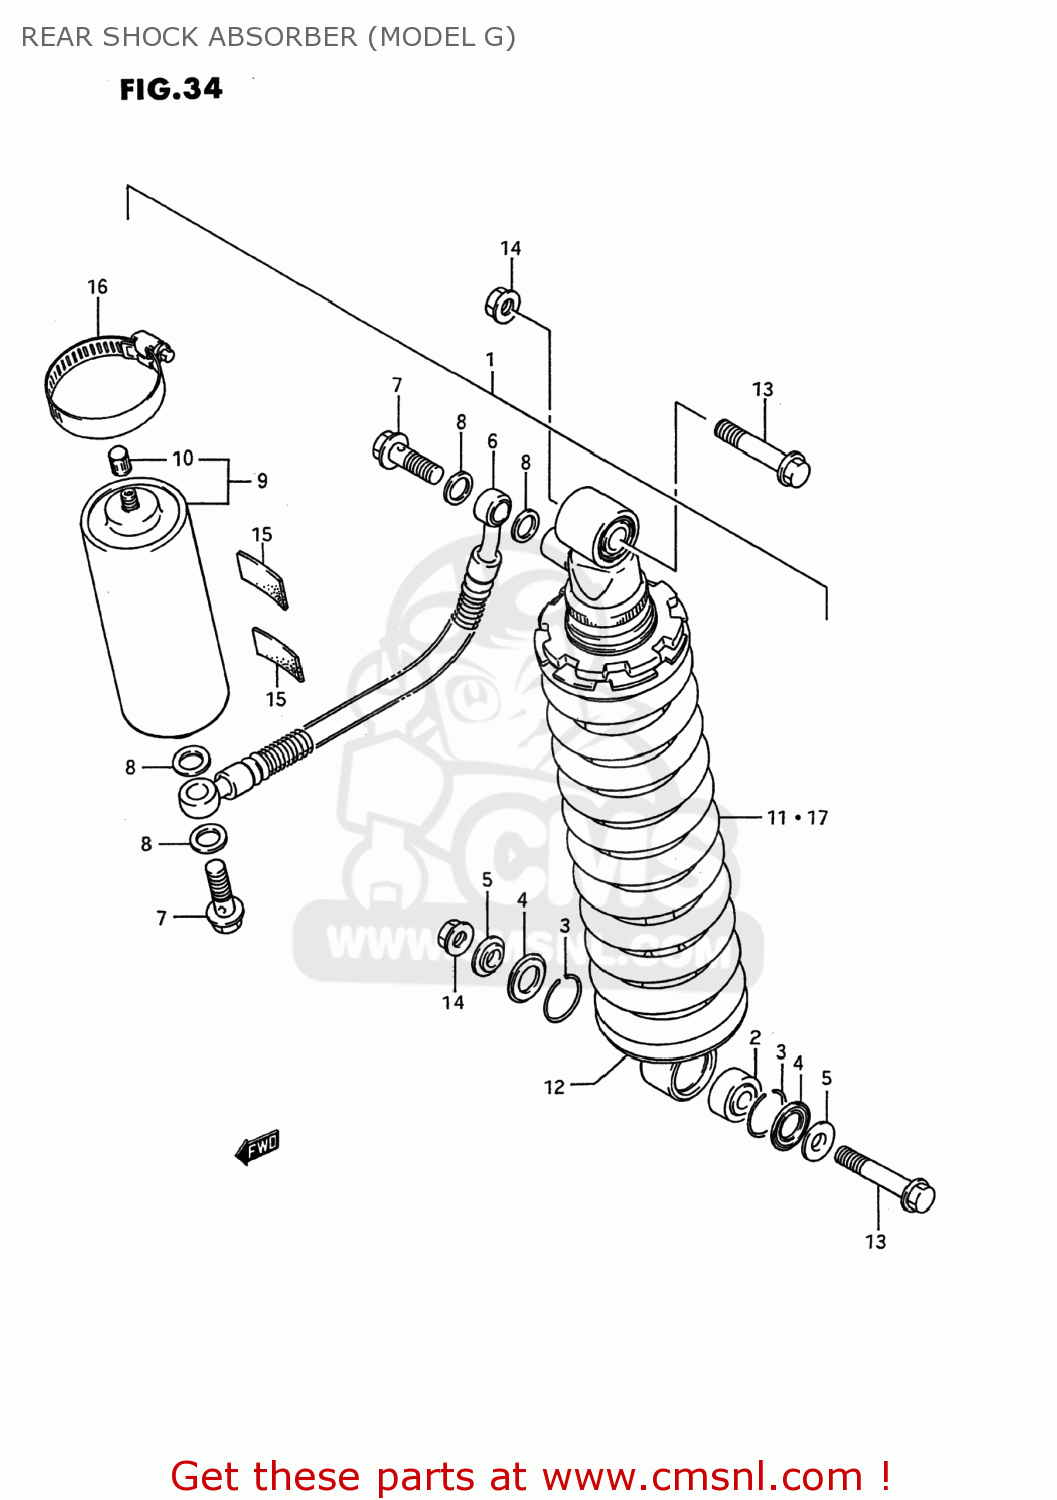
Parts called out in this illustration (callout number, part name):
1	ABSORBER ASSEMBLY,REAR SHOCK
2	BEARING,REAR SHOCK ABSORBER
3	RING
4	DUST SEAL,RR SHOCK
5	COLLAR
6	HOSE
7	BOLT,REAR SHOCK ABSORBER
8	WASHER(10X15X1.5)
9	RESERVE TANK,REAR SHOCK
10	CAP,VALVE AIR
11	SPRING
12	SEAT, SPRING
13	BOLT,RR CUSHION ROD UPR
14	NUT
15	CUSHION,REAR SHOCK ABSORBER
16	CLAMP
17	SPRING,REAR SHOCK ABSORBER
